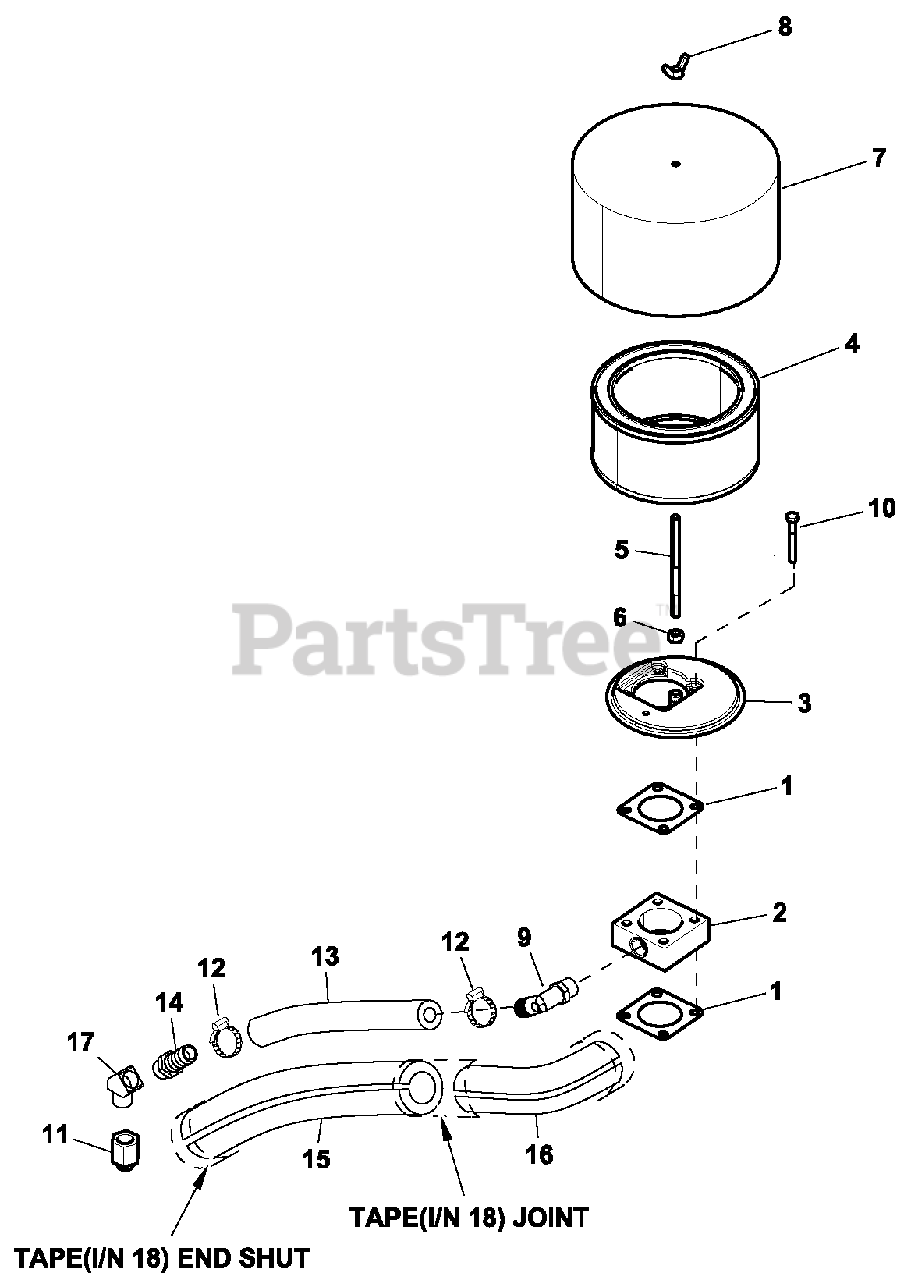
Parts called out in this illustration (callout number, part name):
1	GASKET BOSCH 32 & 40
2	ADAPTOR PCV INTAKE
3	ADAPTOR - CARBURETOR
4	ELEMENT, AIR CLEANER
5	STUDTH 1/4-20X 4-1/2 G 2ZNC
6	NUT HEX 1/4-20 STEEL
7	PLATE, AIR CLEANER TOP 2.4L
8	NUT WING 1/4-20 W/NY INS ST ZN
9	BARBED EL90D 1/2N P T X 3/4
10	SCREW HHC M5-0.8 X 40 G8.8
11	FITTING VENT VALVE COVER
12	CLAMP HOSE #8 .53-1.00
13	HOSE 3/4 ID SAE-30R2 (17.5"LG)
14	BARBED STR 1/2N P T X 3/4
15	PIPE INSULATION (17"LG)
16	PIPE INSULATION ELBO
17	ELBOW 45D STREET 1/2NPT BRASS
18	PIPE INSULATION TAPE (14"LG)
